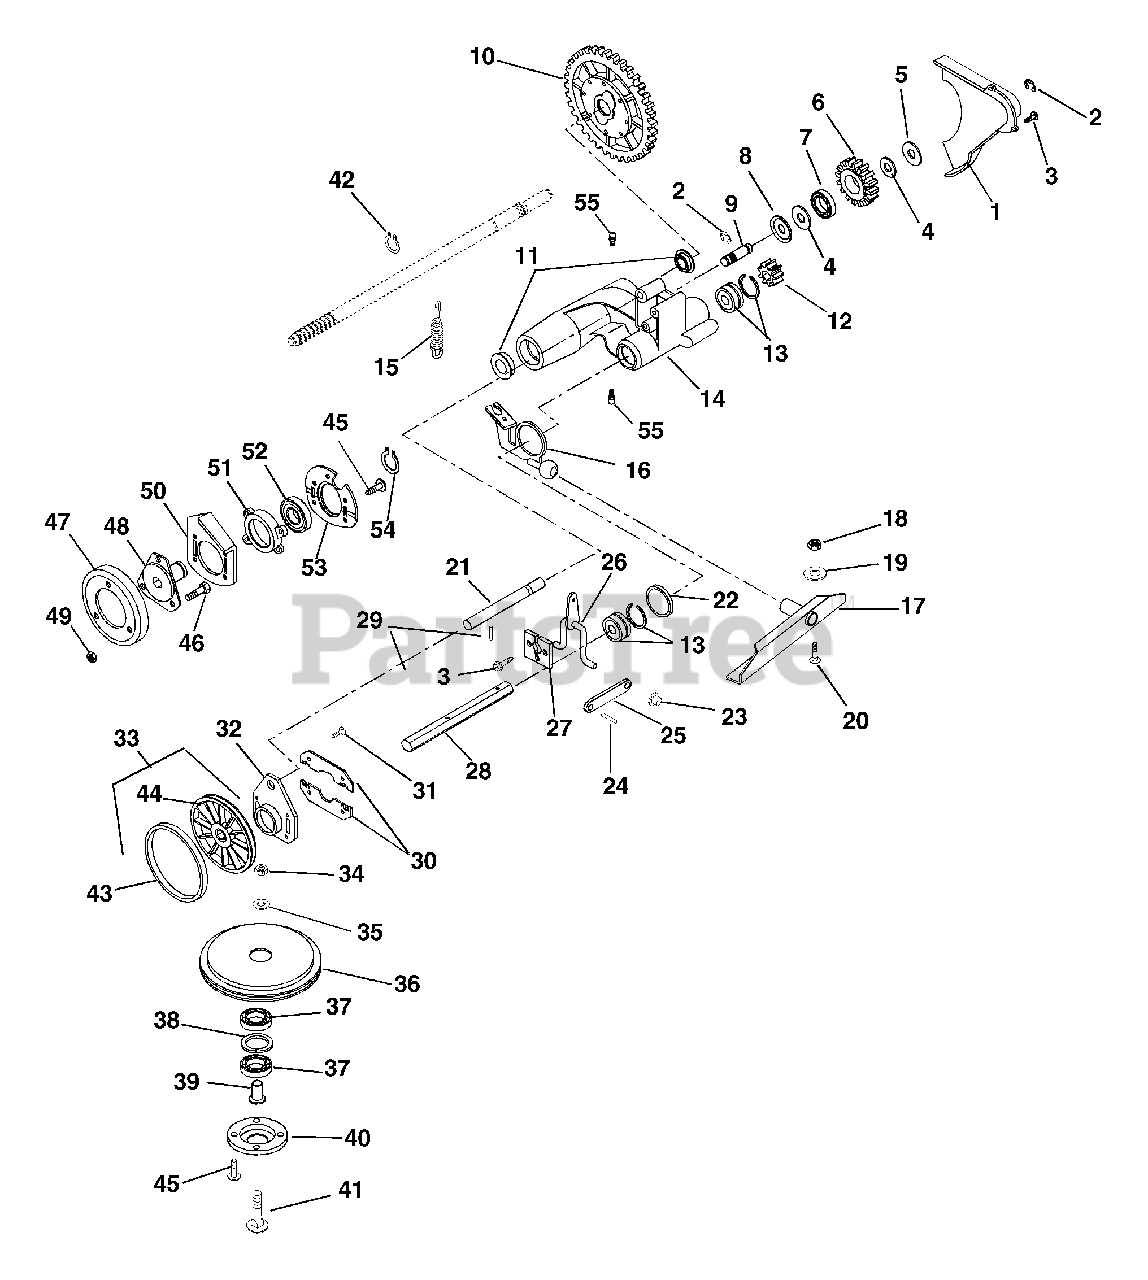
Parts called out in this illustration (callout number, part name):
1	COVER, GEAR
2	RG-RTNG-EXT .438X.035
3	@SCR-TAP 12-24X.50 HWH TR YWZC
4	WSHR-FL-STL .52X.827X.062 YWZC
5	WSHR-FL-STL.531X1.00X.063 YWZC
6	IDLER GEAR
7	BRG-BALL .500X1.38X.437
8	RETAINER
9	IDLER SHAFT
10	DIFFERENTIAL ASSEMBLY
11	BRG-BALL .625X1.383X.50
13	BRG-BALL .562X1.375X.437
14	DRIVE MOUNT
15	SG-TENS .051X.60X2.25 WLD 7.0
16	DRIVE ACTUATOR WELDMENT
17	PIVOT, CHANNEL WELDMENT
18	@NUT-LK-CTR .31-18 YWZC
19	@WSHR-FL-STL.344X.688X.065YWZC
20	@BLT-RHDSSQNK .31-18X.62 G5YZ
21	ROD - GUIDE
22	WSHR-FL-STL 1.390X2.00X.020 PL
23	PUSH NUT, .25
24	PIN-ROLL .125X.50
24	PIN-ROLL .125X.63
25	SHIFT LINK
26	SHIFT ARM WELDMENT
27	RETAINER PLATE
28	HEX SHAFT
29	PIN-ROLL .188X.88
30	THRUST PLATE
31	@SCR-TAP 10-24X.375 HWH YZ TR
32	GUIDE PLATE
33	FRICTION WHEEL ASSEMBLY
34	@NUT-LK-CTR .31-18 YWZC
35	WSHR-FL-STL .328X.87X.179 YWZC
36	FRICTION SHEAVE
37	BRG-BALL .625X1.375X.43
38	WSHR-FL-STL 1.062X1.344X.032PL
39	SPINDLE - BEARING
39	LM BEARING SERVICE KIT
40	RETAINER - BEARING
41	@BLT-RDHDSQNK .31-18X1.75 G5YZ
42	RG-RTNG-EXT .579X.035
43	RING, FRICTION
44	FRICTION WHEEL HUB
45	@SCR-TAP 12-24X.50 HWH TR YWZC
46	@BLT-HEX .25-20X.50 GR5 YWZC
47	DISC, FRICTION - 716 MAT'L
48	FRICTION WHEEL HUB
49	@NUT-LK-CTR .25-20 YWZC
50	BEARING PLATE
51	BEARING RETAINER
52	BRG-BALL 1.0X2.0X.56 (1641)
53	BEARING RETAINER
54	RG-RTNG-EXT 1.00X.042
55	FTG-LUBE .25-28X.256 YWZC
